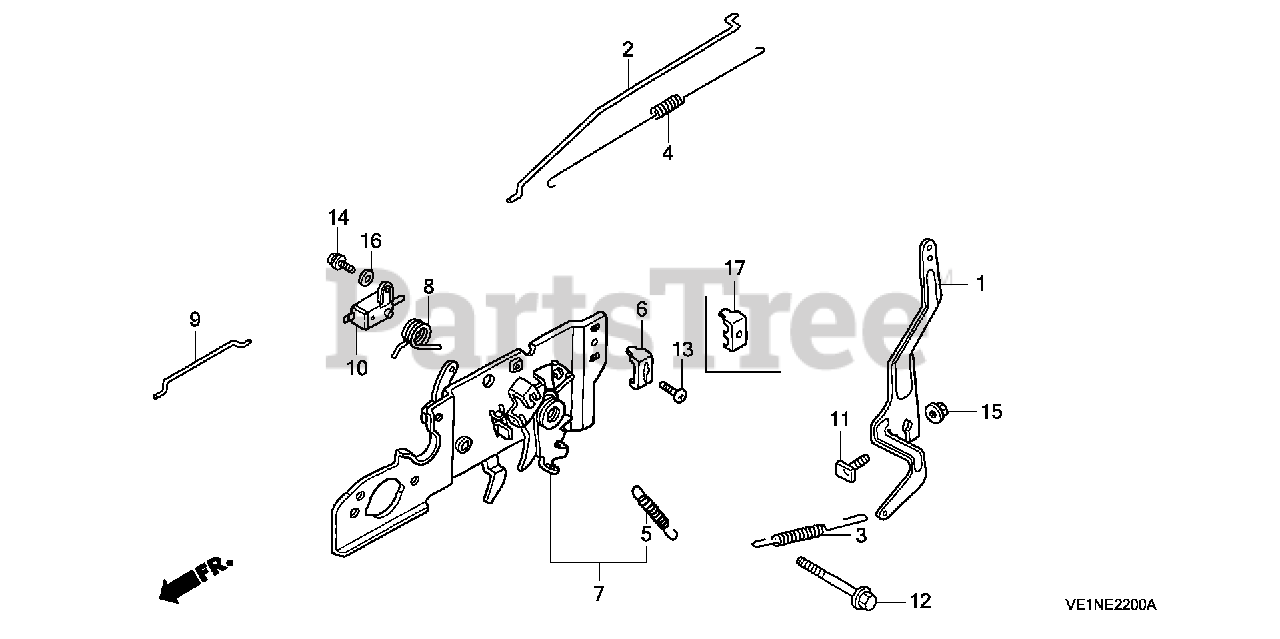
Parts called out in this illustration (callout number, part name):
1	ARM, GOVERNOR
2	ROD, GOVERNOR
3	SPRING, GOVERNOR
4	SPRING, THROTTLE RETURN
5	SPRING, LEVER
6	HOLDER, CABLE
7	BASE, CONTROL
8	SPRING, CONTROL LEVER RETURN
9	ROD, CHOKE
11	BOLT, GOVERNOR ARM
12	BOLT, FLANGE (6X45) (CT200)
13	SCREW, PAN (5X16)
15	NUT, FLANGE (6MM)
17	HOLDER, CABLE
